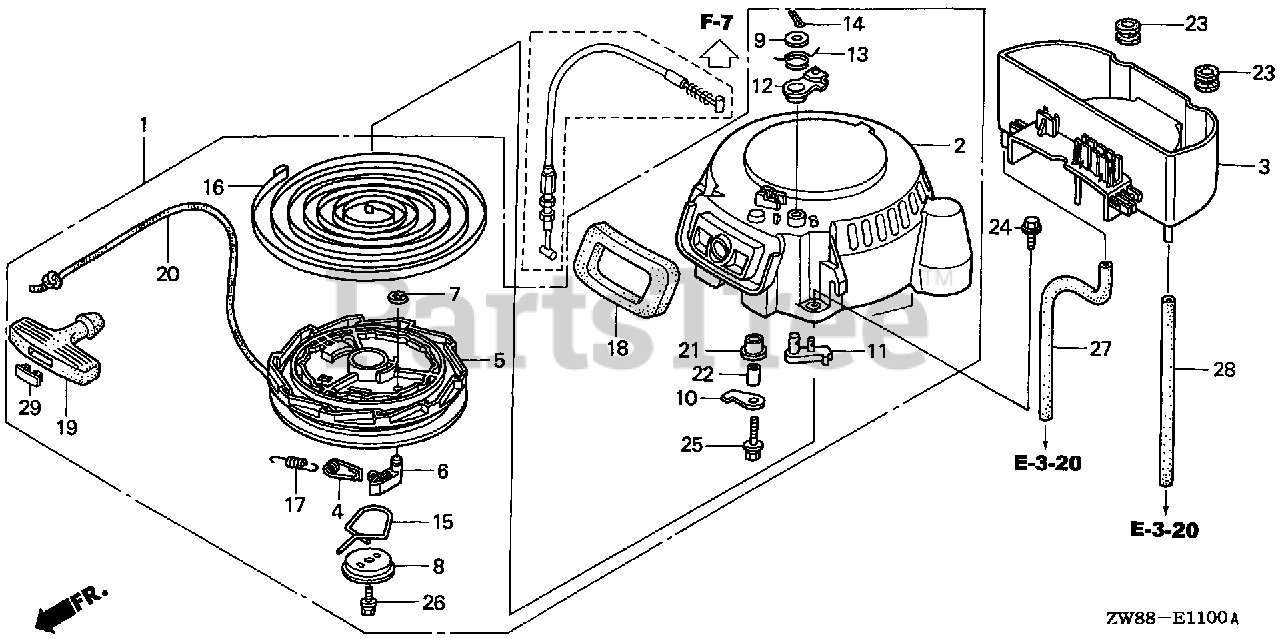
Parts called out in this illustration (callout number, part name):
1	STARTER ASSY., RECOIL
2	CASE, RECOIL STARTER
3	CASE B, STARTER
4	GUIDE, RECOIL STARTER
5	REEL, RECOIL STARTER
6	RATCHET SET, STARTER
6	RATCHET, STARTER
7	RATCHET SET, STARTER
7	E-RING
8	PLATE, FRICTION
10	WASHER, THRUST
11	STOPPER, REEL
12	ARM, STOPPER
13	SPRING, STOPPER
14	PIN, SPLIT
15	SPRING, FRICTION
16	SPRING, RECOIL STARTER
17	SPRING, RETURN
18	SEAL, RECOIL
19	GRIP, STARTER
20	ROPE, RECOIL STARTER (N/A: USE P/N 08550-ZG921-11)
21	ROLLER, STARTER
22	GUIDE, ROLLER
23	GROMMET, ENGINE COVER
24	BOLT, FLANGE (6X22)
25	BOLT, HEX. (6X25)
26	BOLT, HEX. (6X14)
27	TUBE, WATER DRAIN
28	BULK HOSE, VACUUM (8X1000) (8X240)
29	CAP, STARTER KNOB
